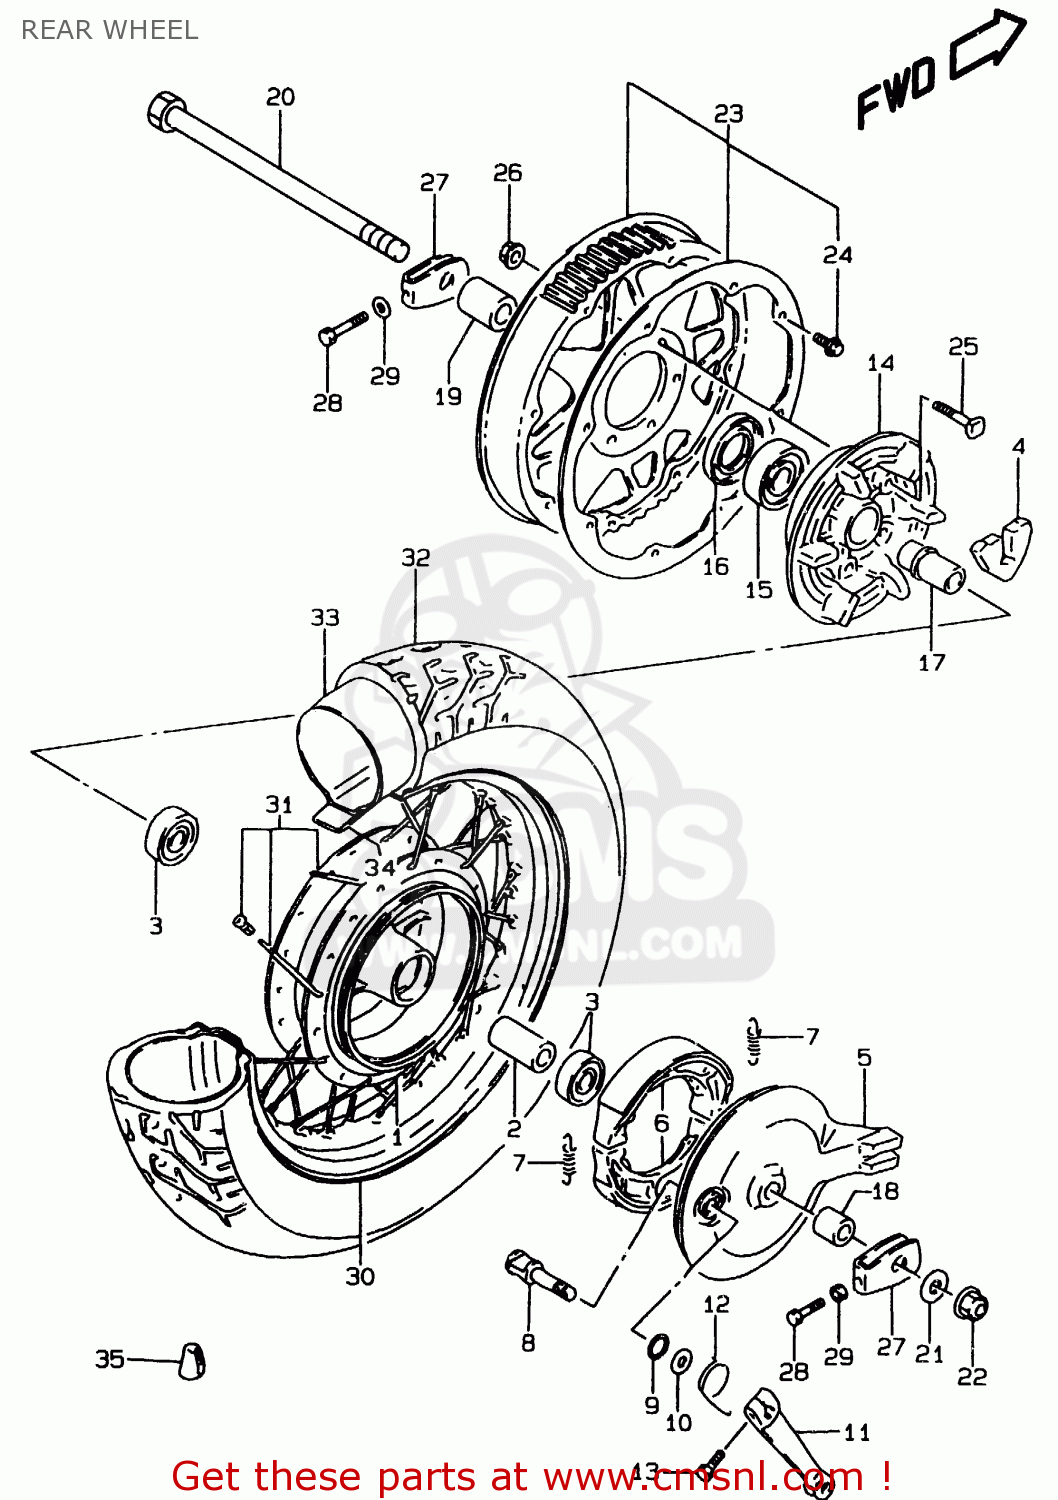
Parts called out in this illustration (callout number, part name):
1	HUB,RR WHEEL
2	SPACER(17.5X25X70)
3	BEARING
4	ABSORBER,RR HUB SHOCK
5	PANEL,RR BRAKE ANCHOR
6	SHOE SET,BRAKE (NAS)
7	SPRING,BRAKE SHOE
8	CAM,BRAKE
9	O RING(D:2.4,ID:14.8)
10	WASHER(15.5X24X1.6)
11	LEVER,RR BRAKE CAM
12	SPRING
13	BOLT. FRONT
14	DRUM,RR SPROCKET MOUNTING
15	BEARING(25X62X17)
16	SEAL,OIL(33X62X7)
17	RETAINER,RR SPROCKET DRUM
18	SPACER(17X28X22.3)
19	SPACER(17X33X35.3)
20	AXLE,RR
21	WASHER(17X30X3.2)
22	NUT
23	SPROCKET,REAR (NT:68)
24	BOLT
25	BOLT(10X40)
26	NUT
27	ADJUSTER,BELT
28	BOLT(8X43)
29	NUT
30	RIM,RR WHEEL WM(2.75X15 M/C)
31	SPOKE SET,RR WHEEL
32	TIRE,RR(140/80-15M/C 67H)
33	TUBE ASSEMBLY,WHEEL,INNER
34	PROTECTOR
35	BALANCER,WHEEL
